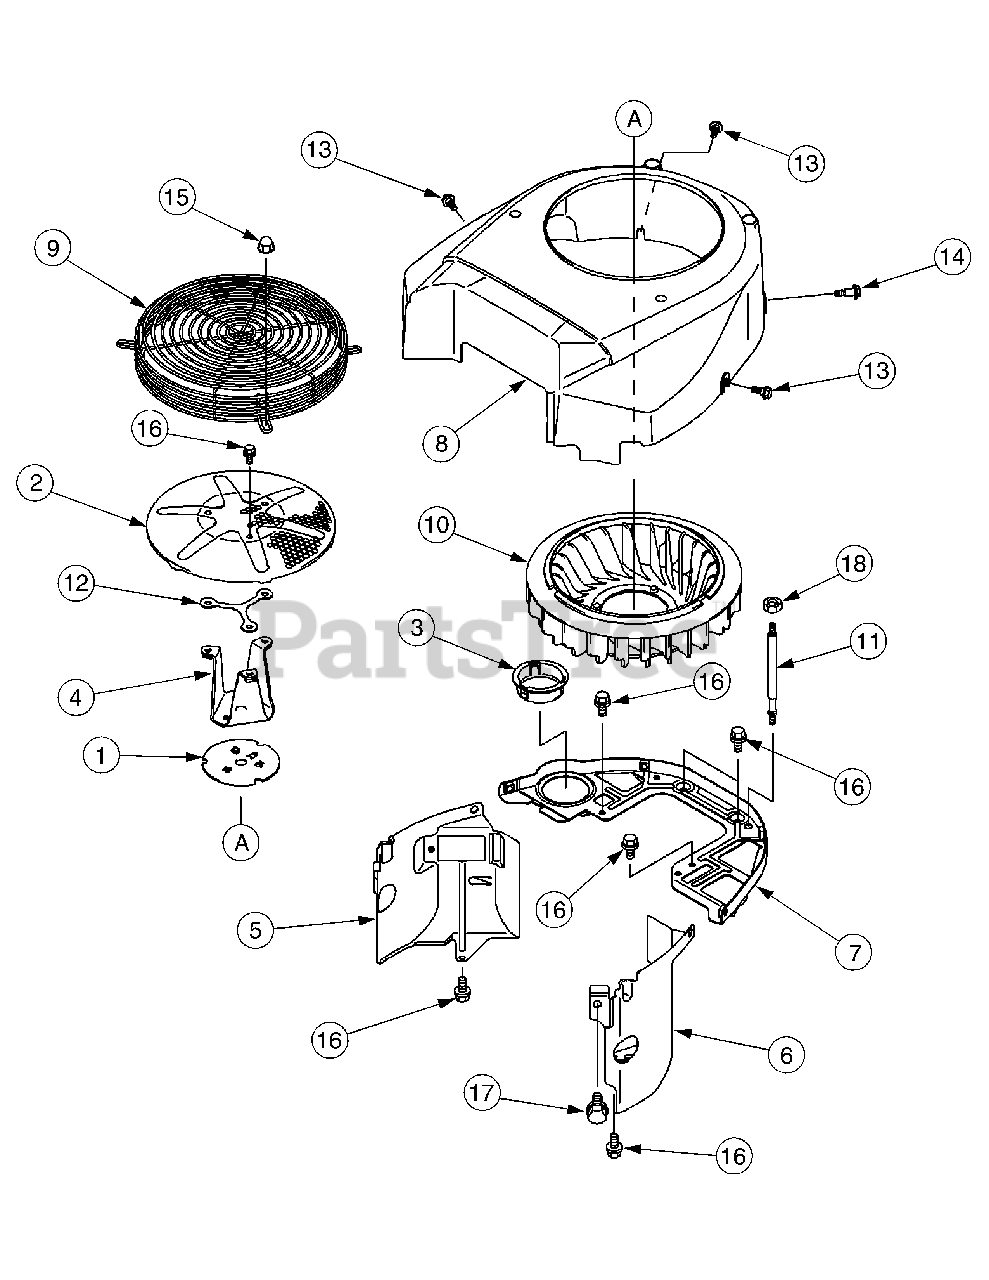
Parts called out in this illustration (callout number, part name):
4	Bracket
5	Shroud, Engine
6	Shroud, Engine
7	Shroud, Engine
8	Label, Maintenance
8	Label, Warnint
11	Stud
12	Spacer
14	Bolt
16	Bolt, Flanged
17	Bolt, Flanged
18	Nut, Hex
